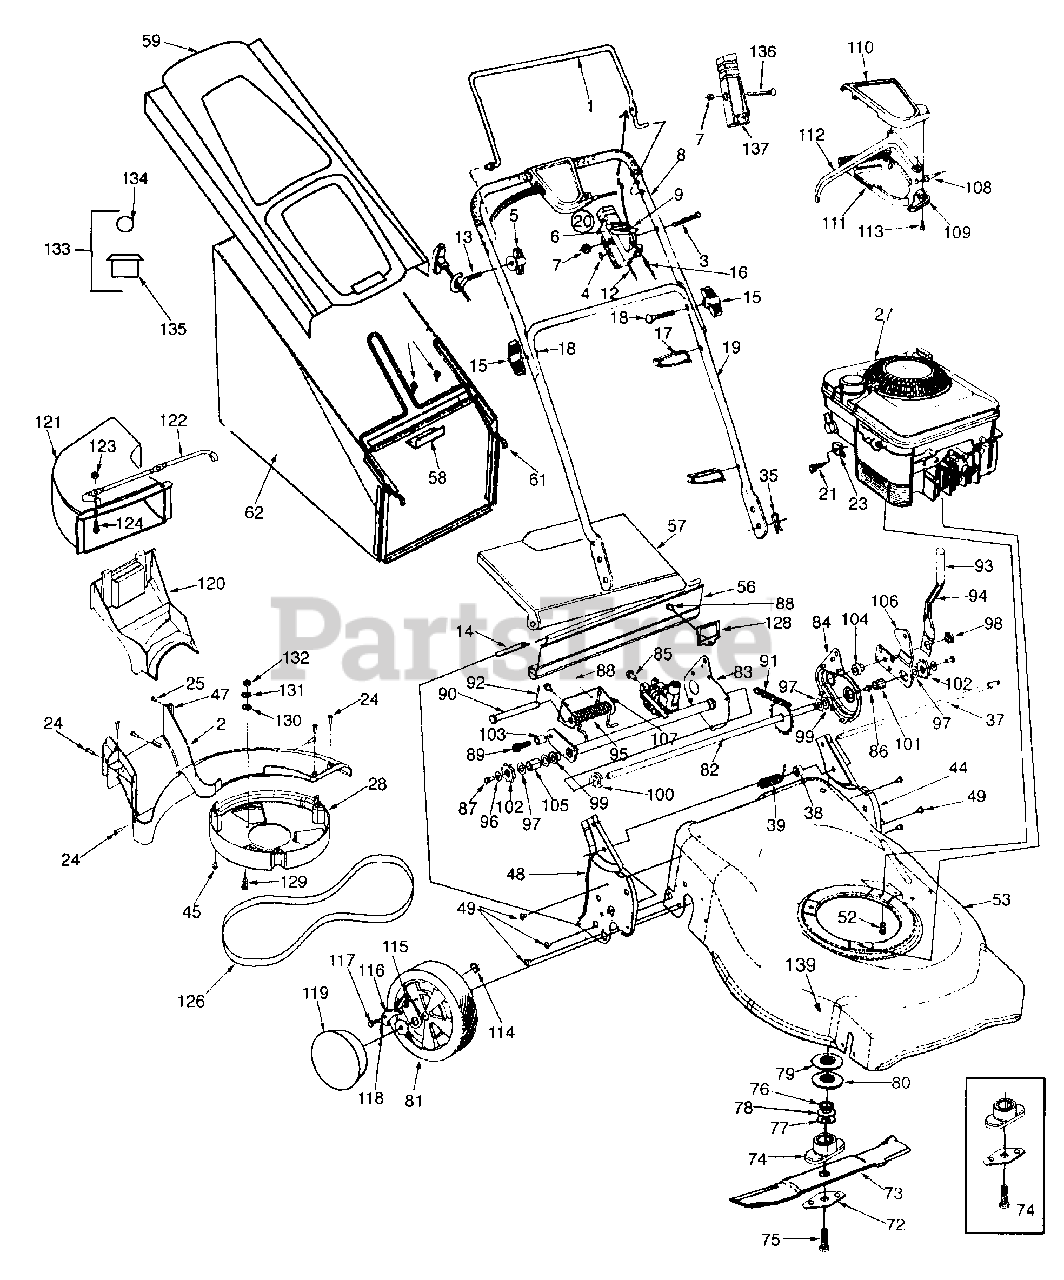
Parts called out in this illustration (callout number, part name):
2	Baffle
3	Oval C-Sunk Mach - Screw
4	Spring Washer .66" ID
5	Handle Knob 1/4-20 Thd.
6	Throttle Body
7	Hex L-Nut 1/4-20
9	Throttle Lever
12	Throttle Control Wire - 47"
13	Rope Guide
14	Wire-47" Lg.
15	Hand Knob
16	Control Cable-55"
17	Cable Tie
18	Cr. Hd. Bolt 5/16-18 x 2" Lg.
20	Throttle Ass'y
21	Hex Self-Tap Scr. #10-32 x.62"
23	Cable Clamp (B & S)
24	Screw H.L. 12-24
25	Screw Mach. B Tapp.
27	Engine
28	Belt Cover
35	Int. Cotter Pin 5/15" Dia.
37	Pivot Rod
38	Spacer .385 I.D.
39	Torsion Spring L.H.
47	U-Nut
52	Hex L-Wash. Hd. Scr. 3/8-16 x 1"
53	21" Deck Ass'y w/ MTD Icon
62	Grass Bag - Black
72	Blade Bell Support
73	21" Mulching Blade w/Star
74	Blade Adaptor Kit w/Star
75	Hex Bolt 3/8-24 x 2.5 Lg.
76	Spacer
77	Fl. Wash. .885 x 1.85 x .06
78	Spr. Wash. .890 x .7 x .04
79	Pulley Half - Upper
80	Pulley Half - Lower
81	Wheel Assembly
82	Axle Assy: RR
86	Scr. TT 1/4-20
87	Hx Cap Screw 1/4-20
88	Hex Washer Screw 1/4-20 x .625
89	Scr 3/8 - 16 x 1.25
90	Pin - Clv. .500 Dia. x 4.62 Lg.
91	Chain:Endless 48:.500P x 22 Lg.
92	Pin-Cotter.125 O.D. x.75
93	Grip-Foam
94	Spring Lever
95	Torsion Spring
96	Bell Washer .265 x 75 x .062
97	Wash. Flat .508 I.D. x 1.0 O.D.:.020
98	Nut - Shoulder .625 x .165 Lg.
99	Bearing-Flg Hex
100	Bearing-Flg. Hex
101	Bearing-Sleeve
102	Ratchet Wheel
103	Spacer - .385 x .625 x .700
104	Spacer-Shld..385 I.D.x.715 Lg.
105	Spacer Slv..520 I.D. x.950 Lg.
109	Mounting Cap
110	Control Cover - Upper
111	Control Cover - Lower
112	Lever
113	Screw #10-16 x .625
114	Weld Top L. 1/4-20
115	Pawl Plate
117	Shldr, Scr. .340 x .285
118	Spring, Ratchet
119	Hub Cap
120	Mulch Plug
121	Chute Deflector
122	Chute Mounting Rod
123	Hex-L-Nut 1/4-20 thd.
124	Mach. Scr. 1/4-20
126	Belt
130	Lockwasher 1/4" Reg.
131	Fl. Wash. .271 x .630 x .065
132	Nut 1/4-20
136	Scr. 1/4-20:1.31 Lg.
137	Housing
139	Spacer
